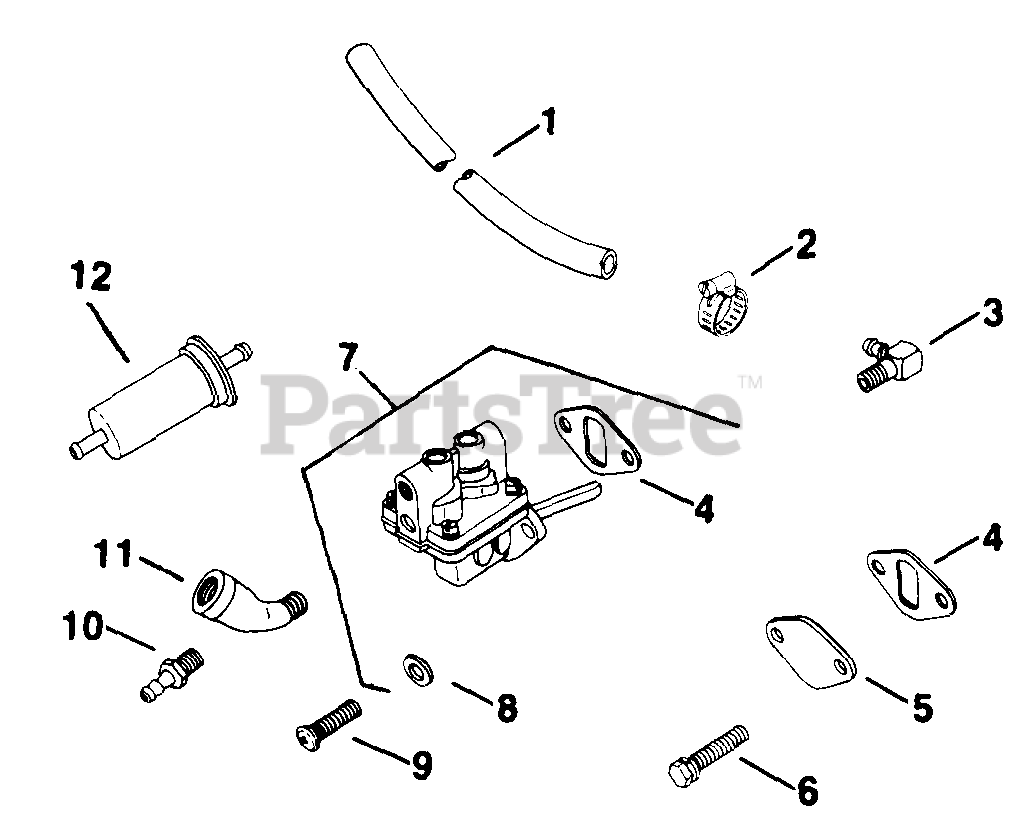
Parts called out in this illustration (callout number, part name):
1	LINE - USE 25 353 10
2	CLAMP, HOSE 1/2" USE 25 237 14-S
3	HOSE - USE 25 155 02
4	GASKET - USE 25 041 05
8	Washer, plain
9	SCREW, POZ TRS HD 1/4-20X5/8" - DISCONTINUED
